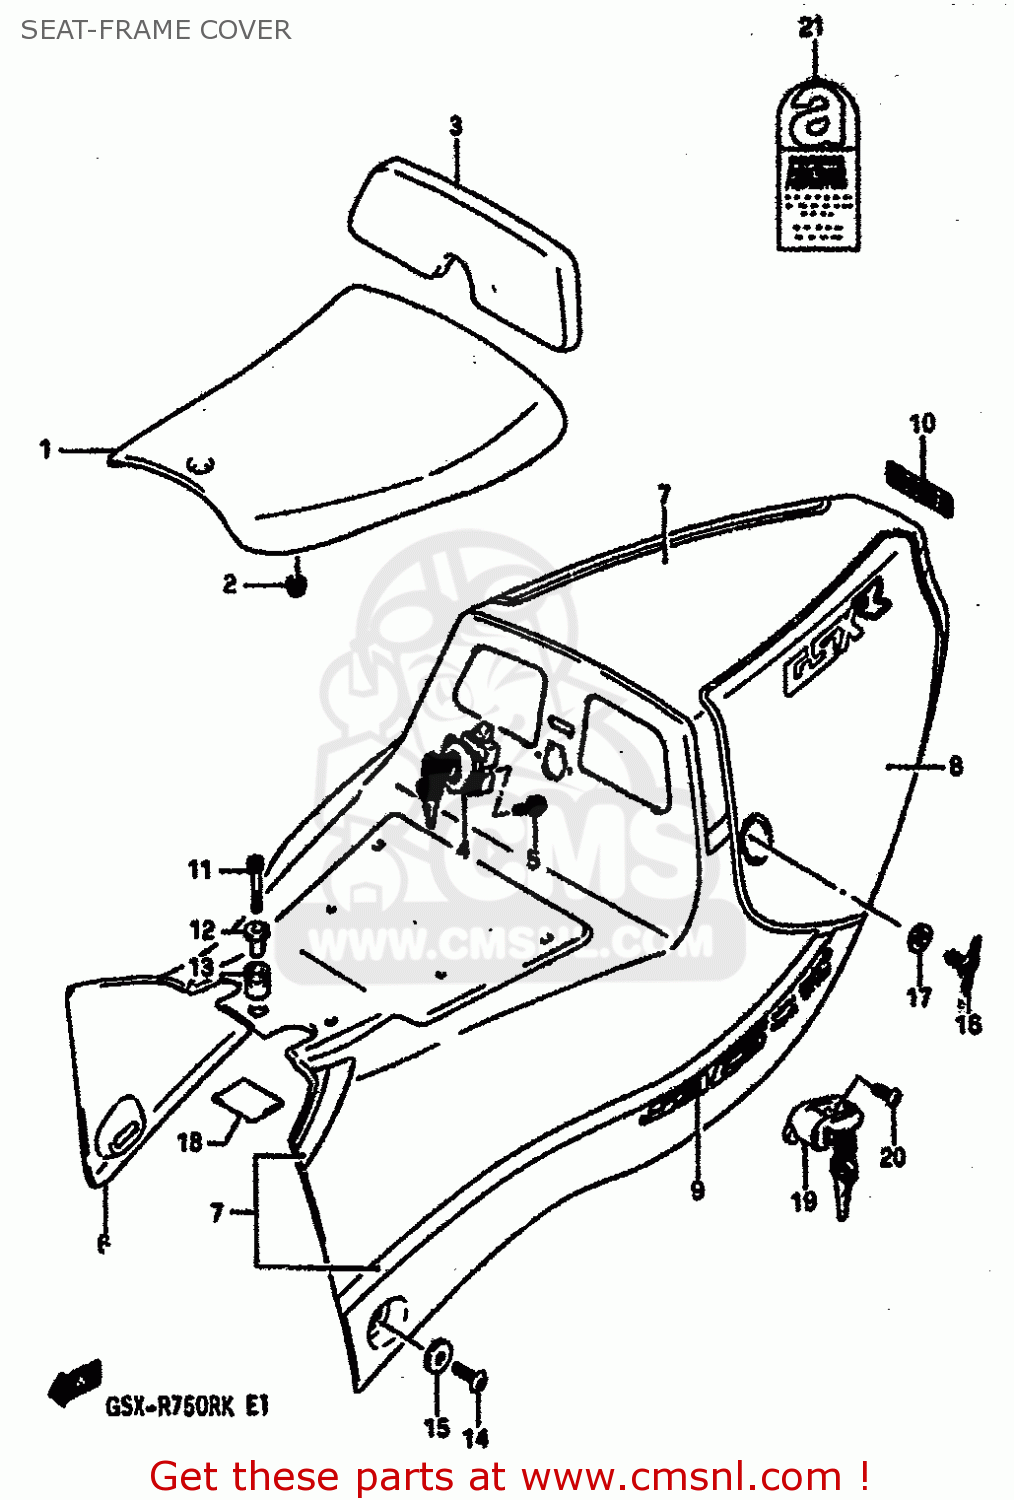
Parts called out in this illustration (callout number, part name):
1	SEAT (BLACK)
2	NUT
3	BACKREST,SEAT (BLACK)
4	LOCK SET,BACKREST
5	SCREW
6	COVER ASSY,FRAME
7	TAPE SET,REAR SIDE
8	TAPE,FRONT RH
9	EMBLEM,FRAME COVER
10	EMBLEM,SUZUKI
11	BOLT
12	COLLAR,FR
13	CUSHION
14	SCREW(6X16)
15	WASHER (6.5X24X1.2)
16	SCREW(8X16)
17	WASHER (8.2X20X1.6)
18	PROTECTOR,FRAME COVER FR
19	LOCK SET,HELMET
20	SCREW
21	LABEL,ASBESTOS WARNING
